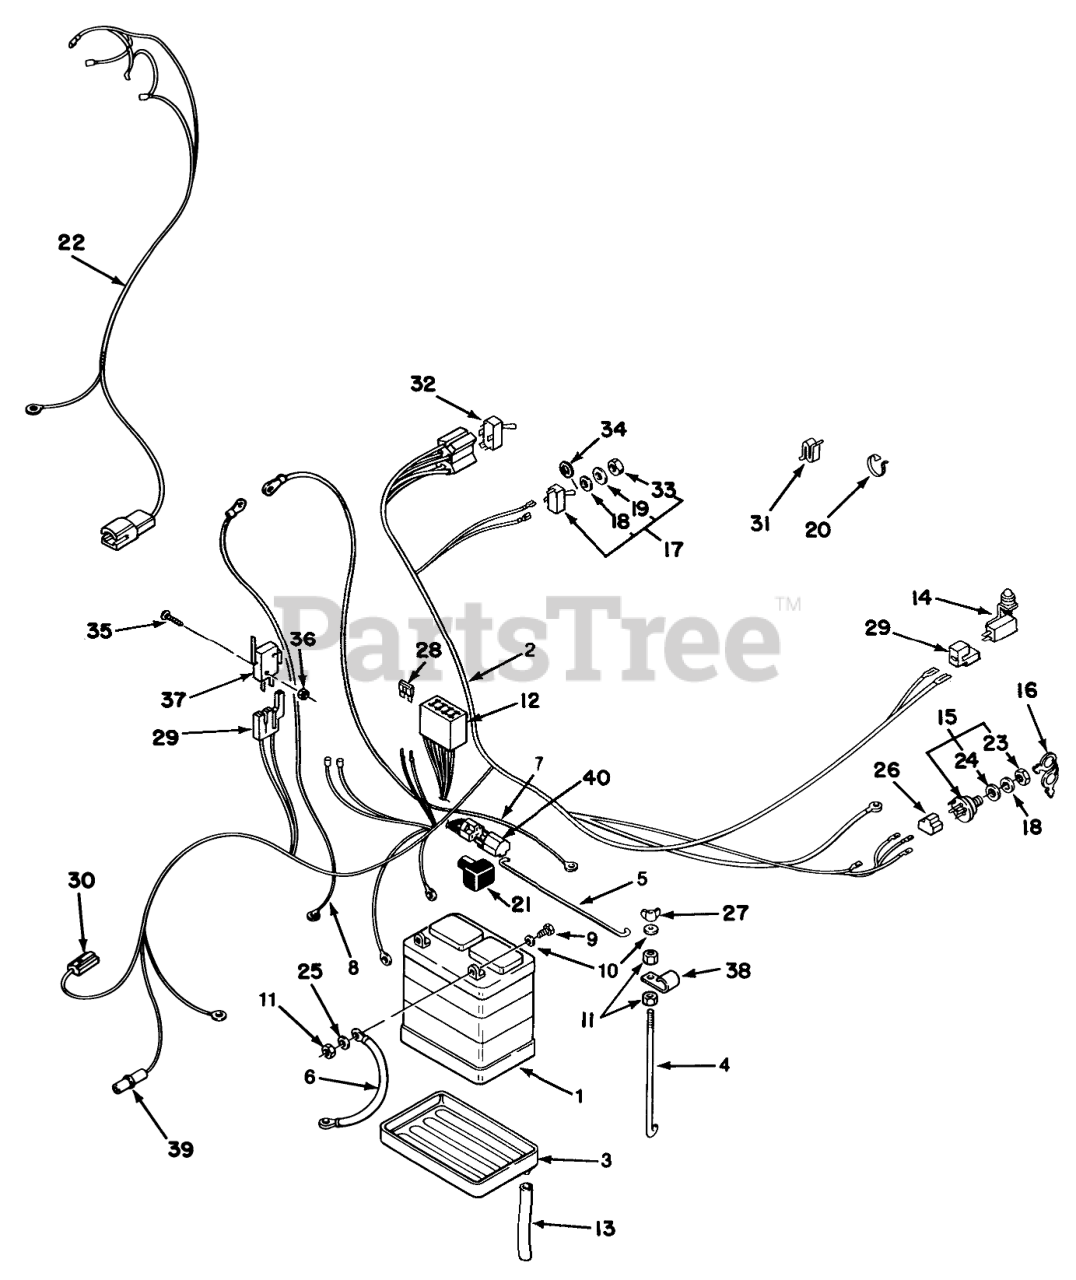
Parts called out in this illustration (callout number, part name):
1	Battery
2	Harness Wire (Incl. Ref. #12, 26 & 29)
3	TRAY-BATTERY
5	ROD-BATTERY HOLD DWN
6	WIRE - 14" BLACK
7	WIRE - 14" BLACK
8	ASS'Y-WIRE
9	SCREW-HH
10	WASHER-FLAT
11	NUT-HEX
12	FUSE-HOLDER 4 WAY
13	TUBE-BATTERY DRAIN
14	SWITCH-SEAT
15	Switch-Ignition (Incl. Ref. #23-24)
16	Key
17	Switch-Light (Incl. Ref. #33 & 34)
18	Washer
19	Washer
20	PLASTIC TIE
21	Boot
22	HARNESS-HEADLIGHT
24	LOCKWASHER
25	WASHER-LOCK
26	CONNECTOR-5 WAY-SERV
27	NUT-WING
28	FUSE-BLADE, 15 AMP
29	CONNECTOR BODY
30	CONNECTOR BODY ELECT
31	SPEED CLIP
32	PTO-SWITCH W/COVER
34	TAB-WASHER
35	Screw
36	NUT HEX 4-40 ELAST
37	SWITCH - CLUTCH
38	CLAMP
39	SOCKET HOUSING
40	RELAY
